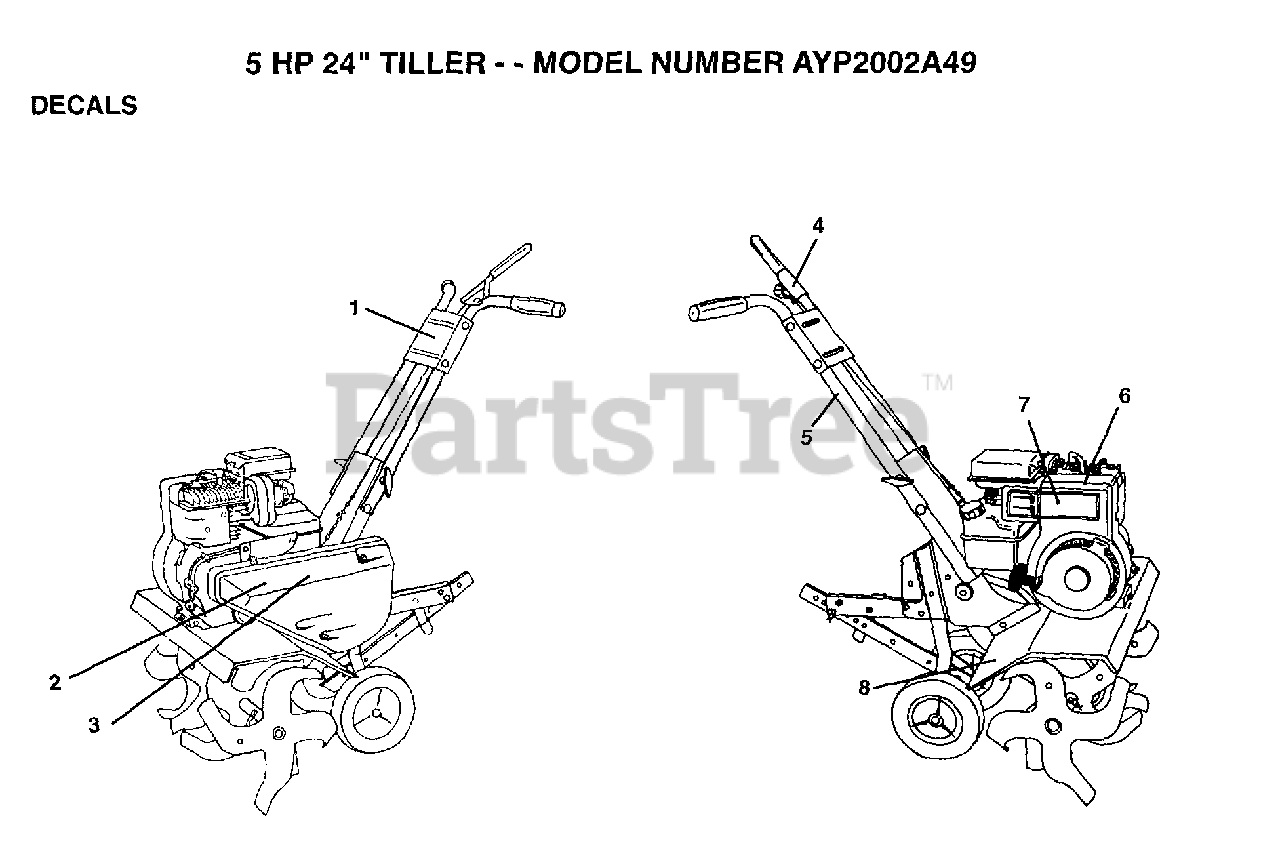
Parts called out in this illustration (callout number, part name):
1	DECAL CTRL PANEL
3	DECAL BELT GUARD
4	DECAL TI
5	DECAL TI
8	DECAL TI
